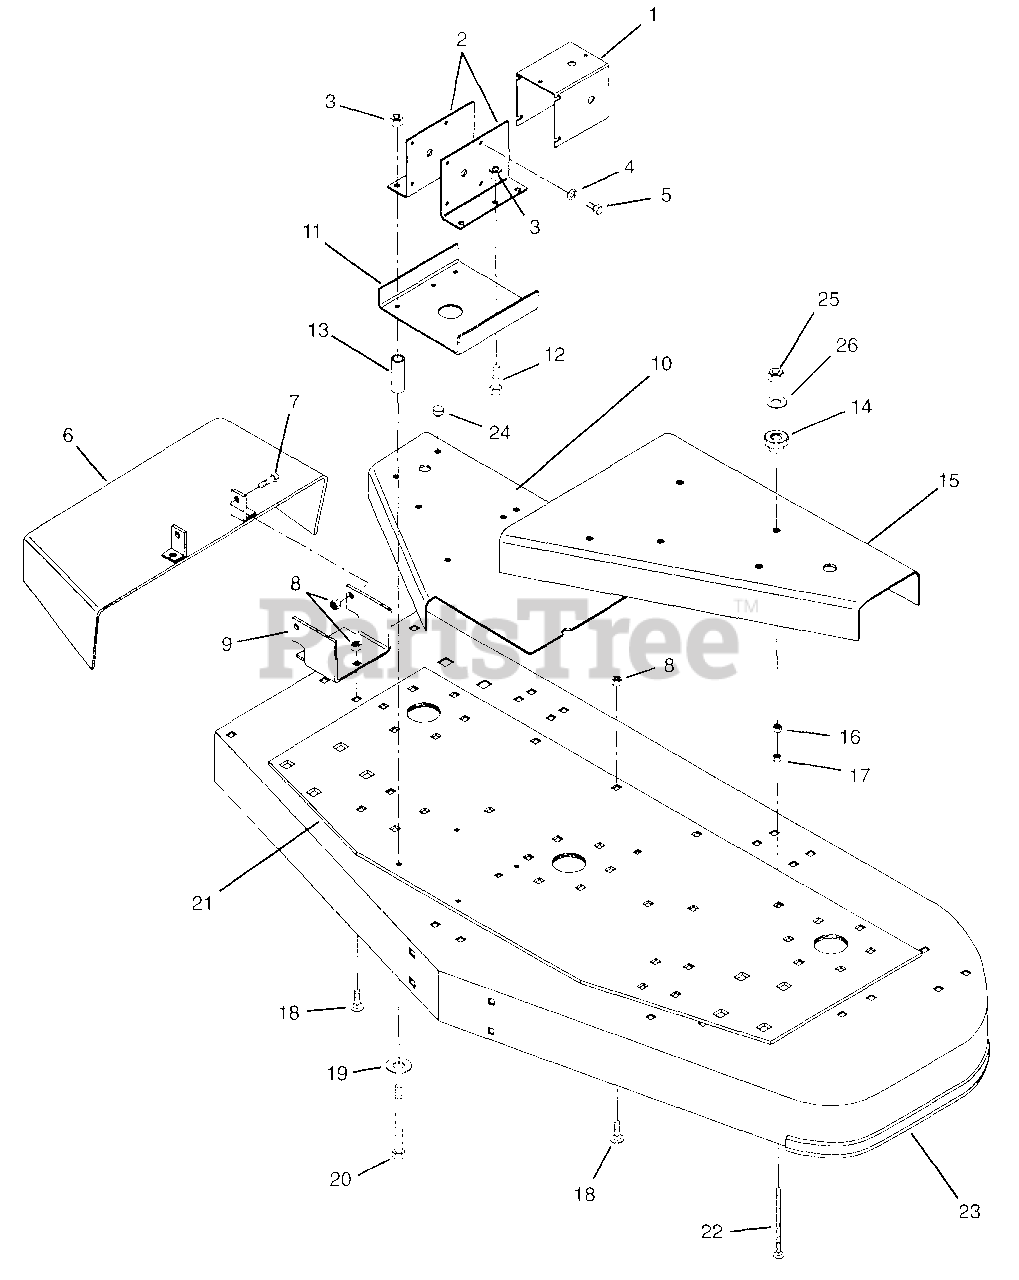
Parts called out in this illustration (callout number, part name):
1	Shield, U-Joint
2	Bracket, Gearbox Mounting Right Hand
2	Bracket, Gearbox Mounting Left Hand
3	Nut-Locking-Nylon .50-13 Grade 5
4	Washer-Lock .375 x .094
5	Bolt-Hex .380-16 x .875
6	Weldment, Discharge Chute
7	Bolt-Hex .375-16 x 1.00 Grade 5
8	Nut-Locking-Nylon .375-16 Grade 2
9	Bracket, Discharge
10	Cover, Belt Right Hand
11	Plate, Support
12	Bolt-Hex .50-13 x 1 Grade 5
13	Spacer .562 x 1.00 x 2.00
14	Knob
15	Silk screen, Belt Cover
16	Nut-Locking-Nylon .312-18 Grade 2
17	Nut-Jam .312-18
18	Bolt-Round Head Square Neck .38-16 x 1.0
19	Washer-Flat-Steel .531 x 1.062 x .095
20	Bolt-Hex .50-13 x 3.75
21	Plate, Deck Support
22	Bolt-Round Head Square Neck .31-18 x 4.0
23	Weldment, 72" Deck
24	Button-Bumper
25	Washer-Flat-Steel .323 x .625 x .062
26	Nut-Locking-Nylon .312-18 w/ Insert Grade 2
